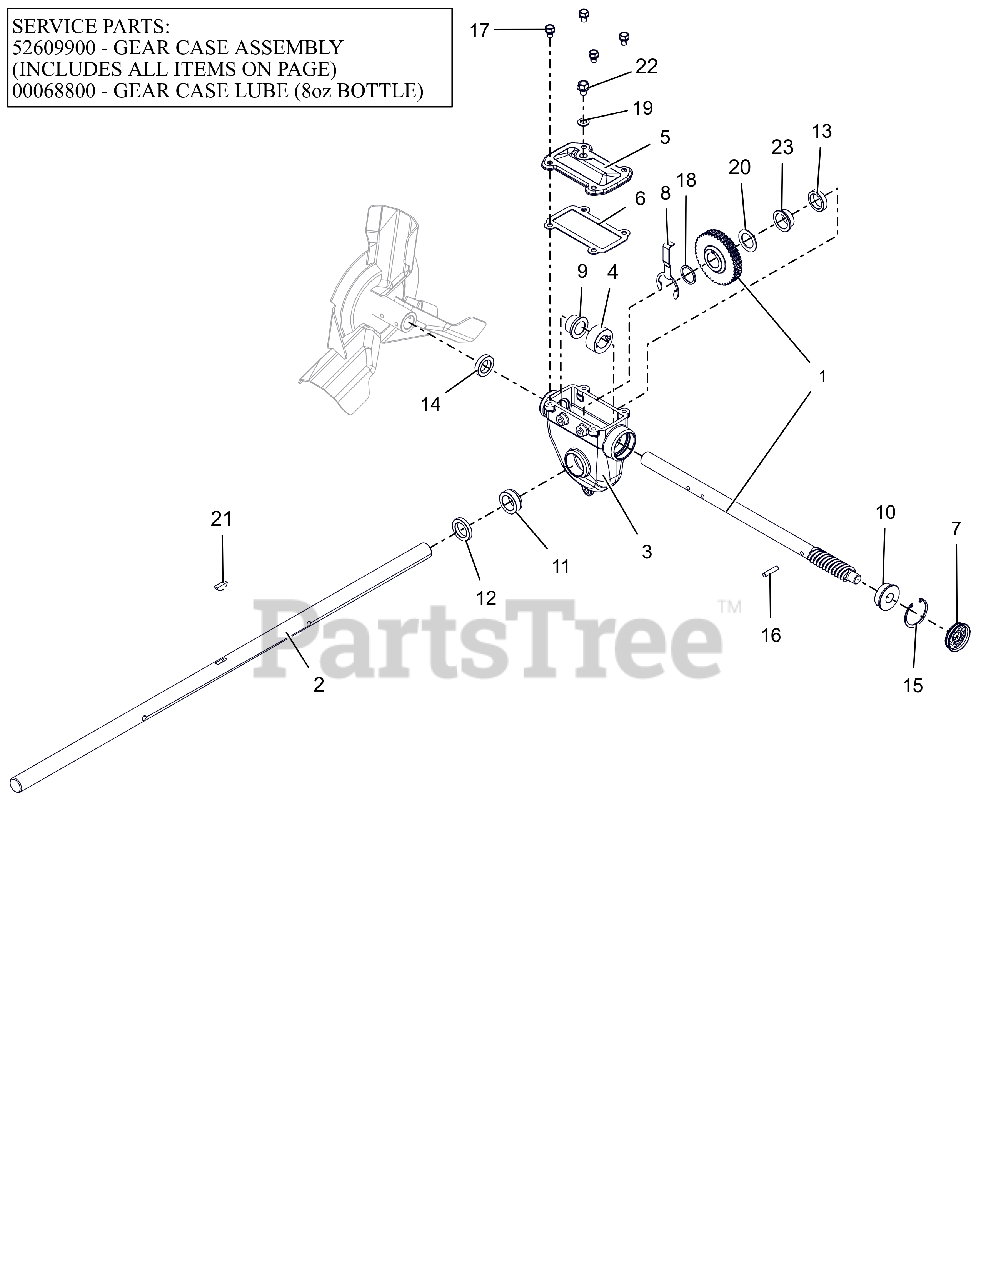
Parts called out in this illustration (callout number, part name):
1	ASSY, WORM SHAFT & GEAR
2	SHAFT, RAKE-36"
3	GEARCASE, LARGE MACHINED
3	GEAR CASE, 36" IRON PRO TOP-LD
3	ARIENS L3 LUBE, 8 OZ BOTTLE
4	THRUST COLLAR, .875"ID SLIPFIT
5	COVER, TOP - LARGE IRON
6	GASKET, TOP - LARGE GEARCASE
7	COVER, GEAR CASE 1.75"
8	BUSHING RETAINER, LARGE
9	BSHG-FLG .879X1.128X.75X1.45
10	BSHG-FLG .628X1.503X.58X1.725
11	BSHG-FLG LARGE, RIGHT
12	SEAL-OIL .999X1.500X.250 TBC29
13	SEAL-OIL .999X1.375X.312 TBC29
14	SEAL-OIL .873X1.375X.312 TBC29
15	RG-RTNG-INT 1.750X.062
16	PIN-STR .250X1.12 6150
17	BOLT, SEMS .31-18X.50 GR5 YWZC
18	WSHR-FL-STL 1.010X1.250X.068YZ
19	WSHR-BND-SEAL .38X.75X.11 GALV
20	WSHR-FL-STL 1.010X1.505X.062YZ
21	KEY-WDRF .25X.875 HRD #A
22	@SCR-ROLOK .38-16X.50 HWH YWZC
23	BSHG-FLG 1.006X1.128X.555X1.45
